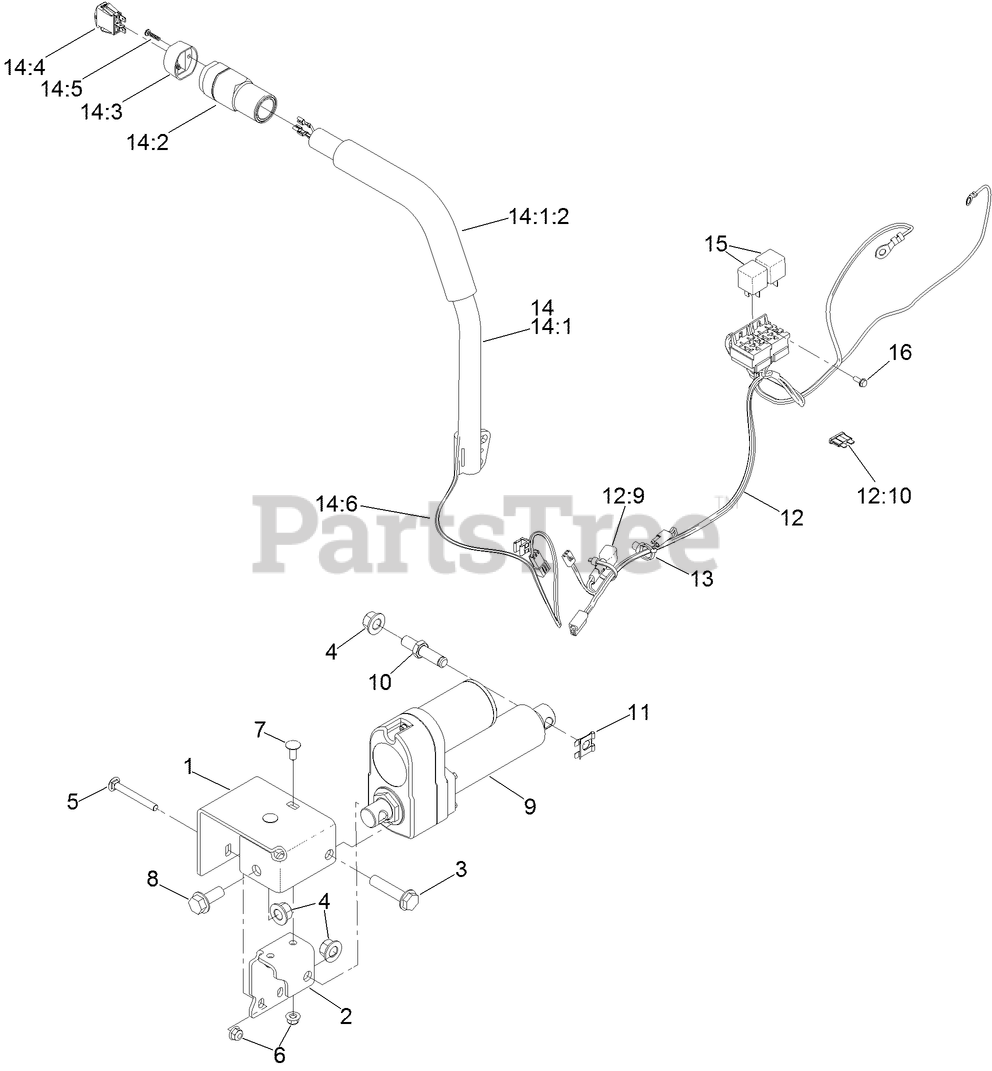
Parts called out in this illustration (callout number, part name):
1	BRACKET-MOUNT, OUTER
2	BRACKET-MOUNT, INNER
3	SCREW-HHF
4	NUT-LOCK
5	SCREW-CARR
6	NUT-HF, NI
7	BOLT-CARR
8	SCREW-HHF
9	ACTUATOR-LINEAR
10	PIN-PIVOT, ACTUATOR
11	CLIP-PIN
12	HARNESS-WIRE, DECK LIFT
12:10	FUSE-BLADE, 20 AMP
13	CLIP-TIE
14	HANDLE ASM-LH
14:1	HANDLE ASM - LH
14:1:2	GRIP-CONTROL, LEVER
14:2	CASE ASM
14:3	CAP-SWITCH
14:4	Air Cleaner Element
14:5	SCREW-PPH
14:6	HARNESS-WIRE, HANDLE
16	SCREW-TAPTITE
